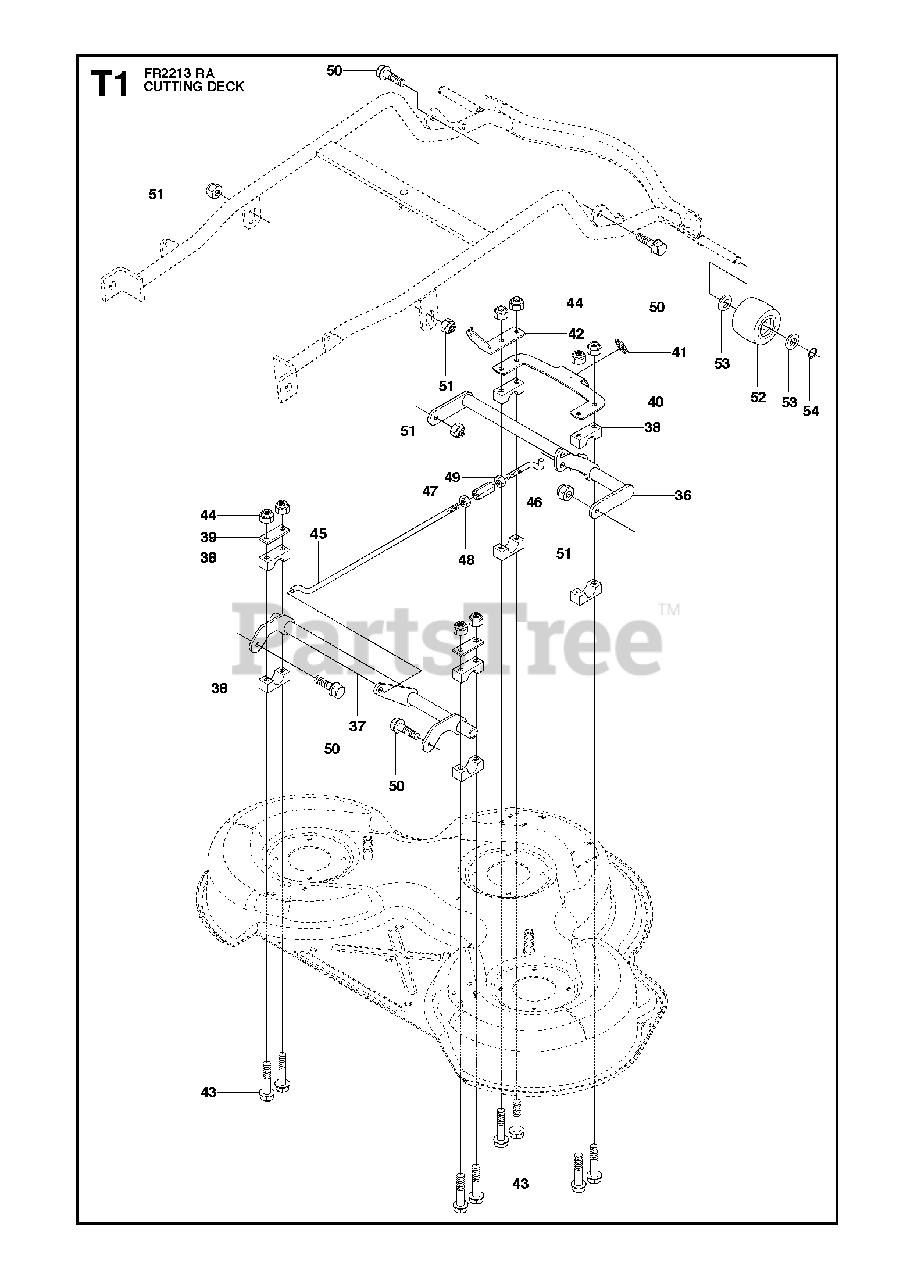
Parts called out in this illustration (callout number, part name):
44	LOCKNUT M8
51	LOCKNUT M8
52	DECK ROLLER, FRONT
54	RETAINING RING SGA 15
